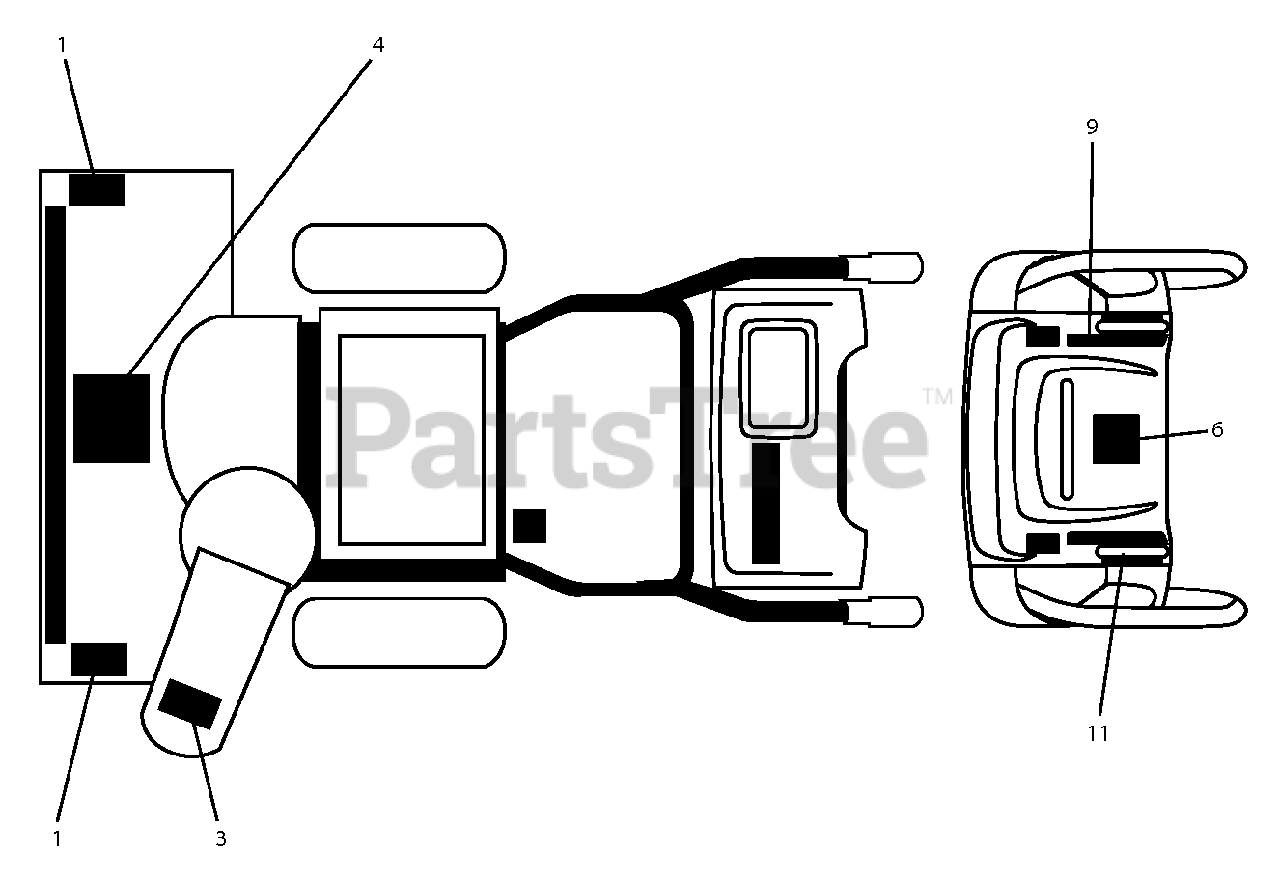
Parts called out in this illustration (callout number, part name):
1	DECAL.SNOWTHR.AUGER
3	Decal, Snow Thrower Chute Safety
4	Decal, Snow Thrower Read Owner's Manual E/F
6	Instruction Panel Decal
9	DECAL.CONS.RT.SPD/LEV/P.WRST
11	DECAL.CONS.LT.SPD/LEV/P.WRST
